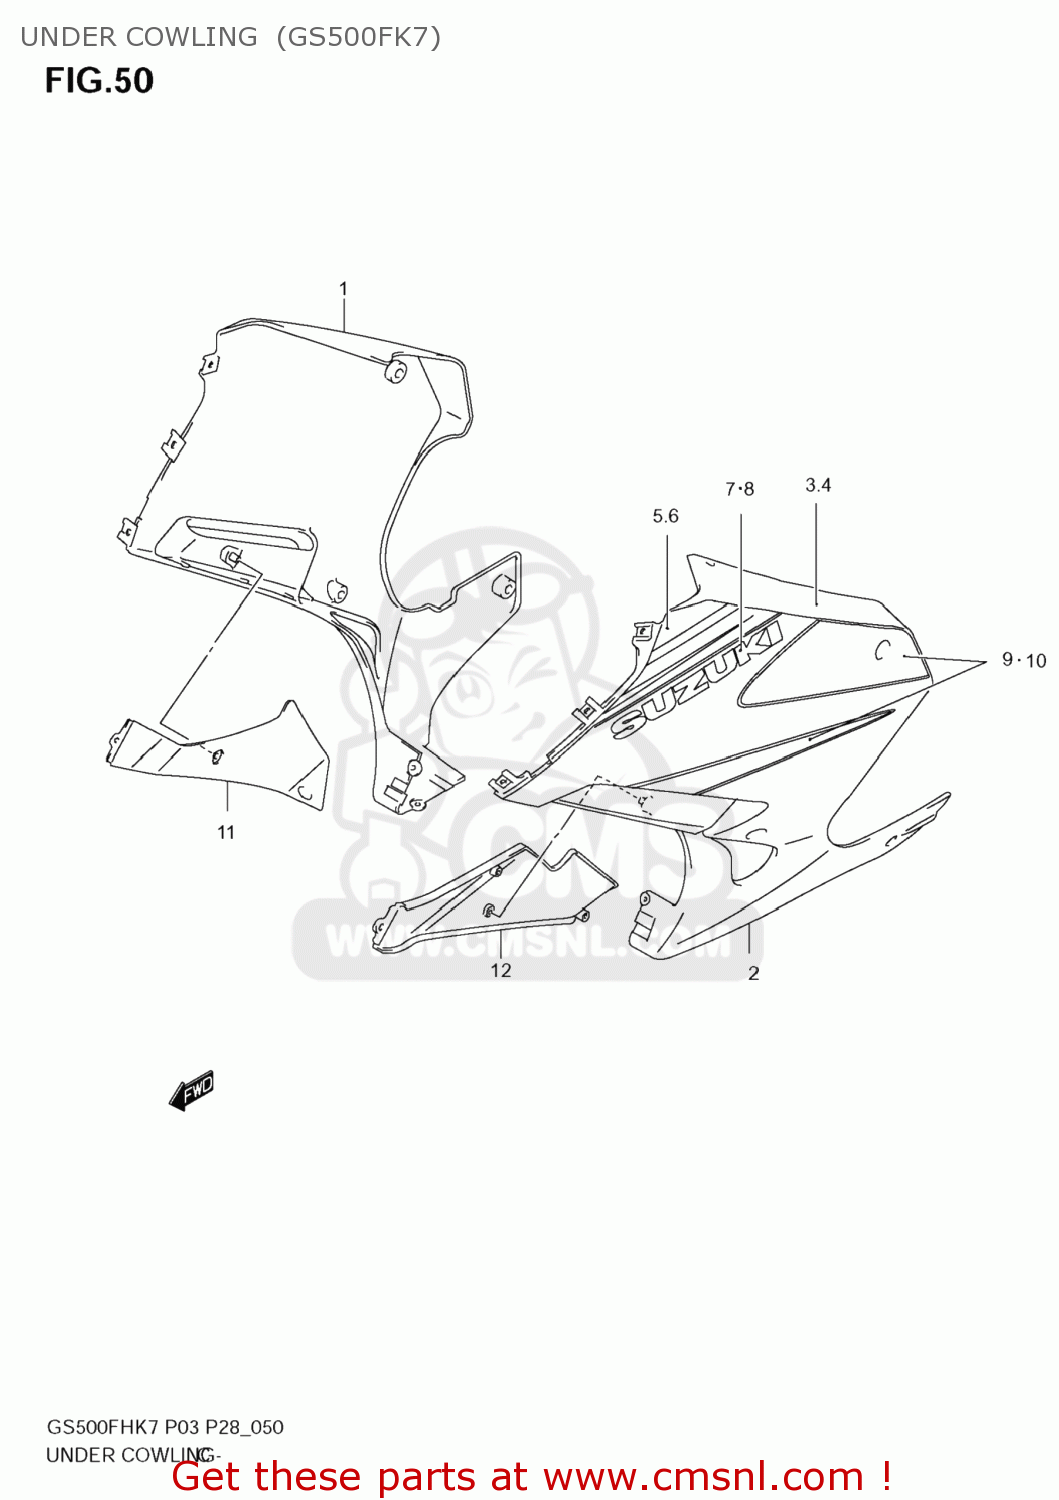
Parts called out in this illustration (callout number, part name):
1	COWL,UNDER RH
2	COWL,UNDER LH
3	TAPE GS500
4	TAPE,UPPER
5	TAPE
6	TAPE
7	EMBLEM"SUZUKI"
8	EMBLEM
9	TAPE SET
10	TAPE SET
11	COWLING, INNER
12	COWLING, INNER
13	SHIELD,UNDER C
14	SHIELD,UNDER C
15	SHIELD,UN. HEA
16	SHIELD,UN.HEAT
